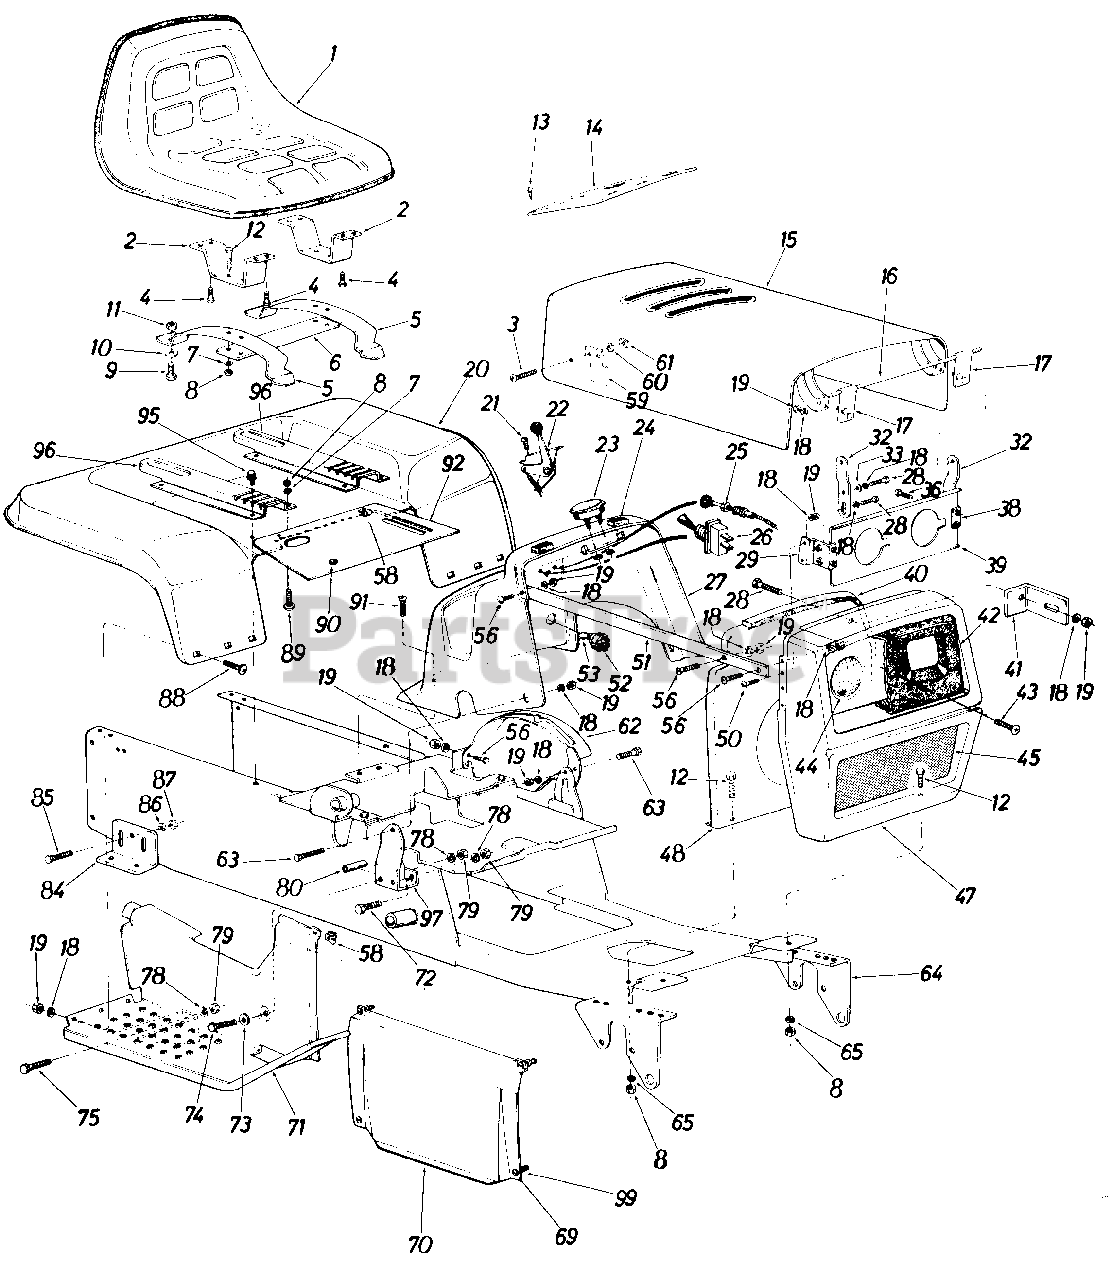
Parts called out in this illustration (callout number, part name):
1	Seat Ass'y. Comp.
2	Seat Support Brkt.
3	Truss Hd. Mach. Scr. #10-24 x.38" Lg.
4	Hex Wash. Hd. Self-Tap Scr. 3/8-16 x .75" Lg.
7	L-Wash. 5/16" Scr.
8	Hex Nut 5/16-18 Thd.*
9	Nylon Scr. 1/2-13 x .75" Lg.
10	Fl-Wash. .531 I.D. x .930 O.D.
11	Hex Cent. L-Nut 1/2-13 Thd.
12	Hex Scr. 5/16-18 x .75" Lg.
13	Self-Tap Oval Hd. Scr. 1/2" Lg.
14	Dash Panel Cover
15	Hood Ass'y.
16	Hinge Rod
17	Hood Hinge Ass'y.
18	L-Wash. 1/4" Scr.
19	Hex Nut 1/4-20 Thd.
20	Rear Fender
21	Fl-Hd. Truss Scr. #10 x .62" Lg.
22	Throttle Control
23	Ammeter
24	Rubber Bumper
25	Choke Control
26	Light Switch
27	Dash Panel
28	Hex Scr. 1/4-20 x .62" Lg.
29	Hood Support Brkt. Ass'y.-R. H.
36	Hex Scr. 1/4-20 x .38" Lg.
38	Hood Support Brkt. Ass'y.-L.H.
41	Heat Shield Brkt.
42	Head Lamp Bezel
43	Truss Mach. Scr. #10-24 x .50" Lg.
44	Head Lamp
45	Grille Screen
50	Truss Mach. Scr. 1/4-20 x .75" Lg.*
51	Grille Strap
52	Ignition Switch
53	Ignition Key
56	Hex Scr. 1/4-20 x .75" Lg.
58	Clip-On Receptacle
59	Hood Spring
60	L-Wash. #10
61	Hex Nut #10-24
62	Speed Control Guide
63	Truss Mach. Scr. 1/4-20 x .75" Lg.*
64	Frame Ass'y.
65	Bell-Wash. 5/16" Scr.
69	1/4-Turn Stud
70	Hood Lower Side Panel
71	Foot Step Panel Ass'y.-R. H.
72	Hex Scr. 3/8-16 x 1.00" Lg. Grade 5
73	Fl-Wash. .385 I.D. x .62 O.D.
74	Hex Scr. 3/8-16 x 3.00" Lg.
75	Hex Scr. 3/8-16 x 1.00" Lg. Grade 5
78	L-Wash. 3/8" Scr.
79	Hex Nut 3/8-16 Thd.*
80	Spacer .375 I.D. x .62 O.D. x 2.00" Lg.
84	Transaxle Support Brkt.
85	Rd. Hd. Rib Neck Scr. 3/8-24
86	L-Wash. 3/8" Scr.
87	Hex Nut 3/8-24 Thd. *
88	Carr. Bolt 1/4-20 x .50" Lg.*
89	Carr. Bolt 5/16-18 x .62" Lg.
90	Snap Bushing
91	Fl-Hd. Self-Tap Scr. 1/4-20 x .62" Lg.
96	Seat Adjustment Brkt.
